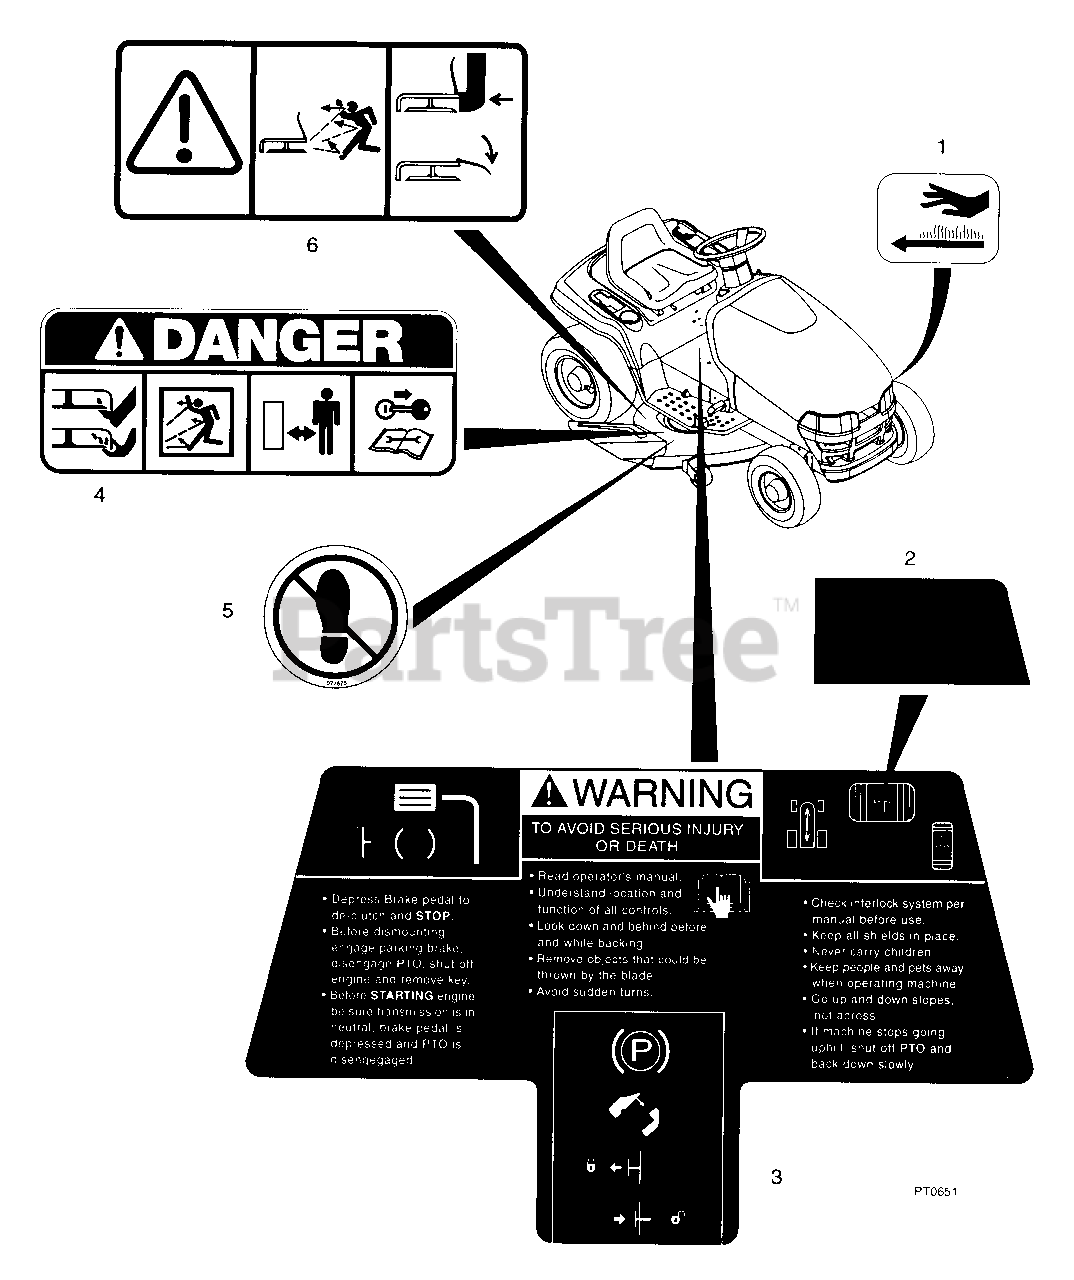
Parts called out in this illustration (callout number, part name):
1	DECAL- HOT SURFACE SYMB.
2	DECAL - COVER
3	DECAL - OPERATING INSTRUCTIONS
3	DECAL- OPER INSTR SIERRA FOREI
4	DECAL- MOWER PAN
5	NO STEP DECAL
6	DECAL- DISCHARGE
